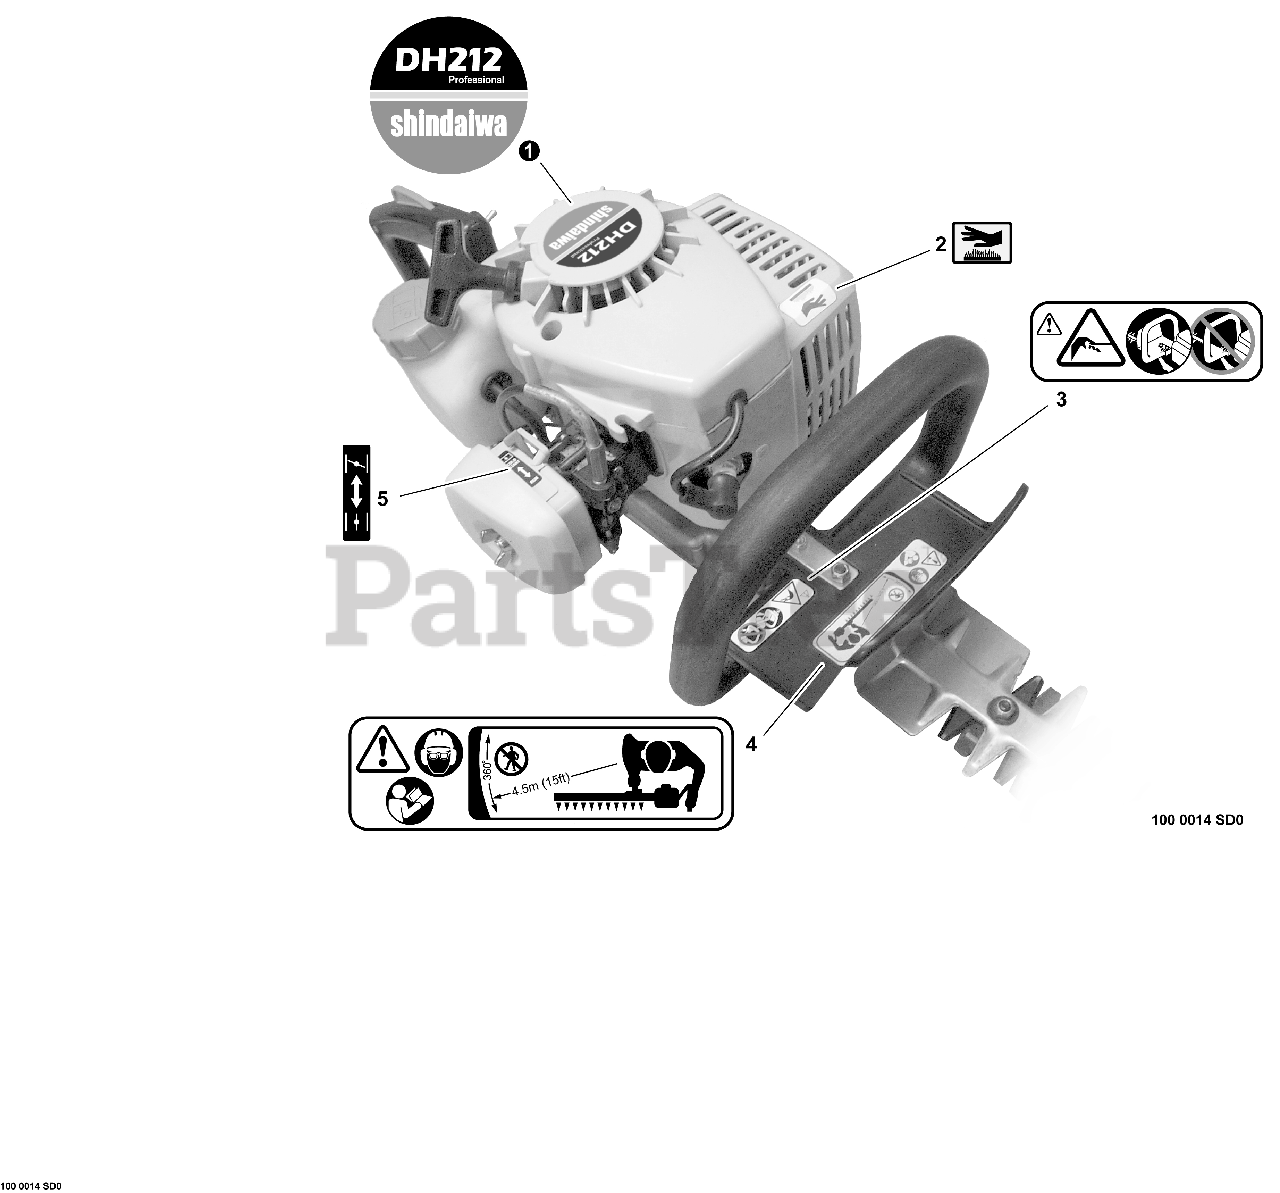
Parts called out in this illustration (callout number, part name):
1	LABEL - MODEL DH212
2	LABEL - HOT SURFACE
3	LABEL - CAUTION
4	LABEL - CAUTION
5	LABEL - CHOKE
